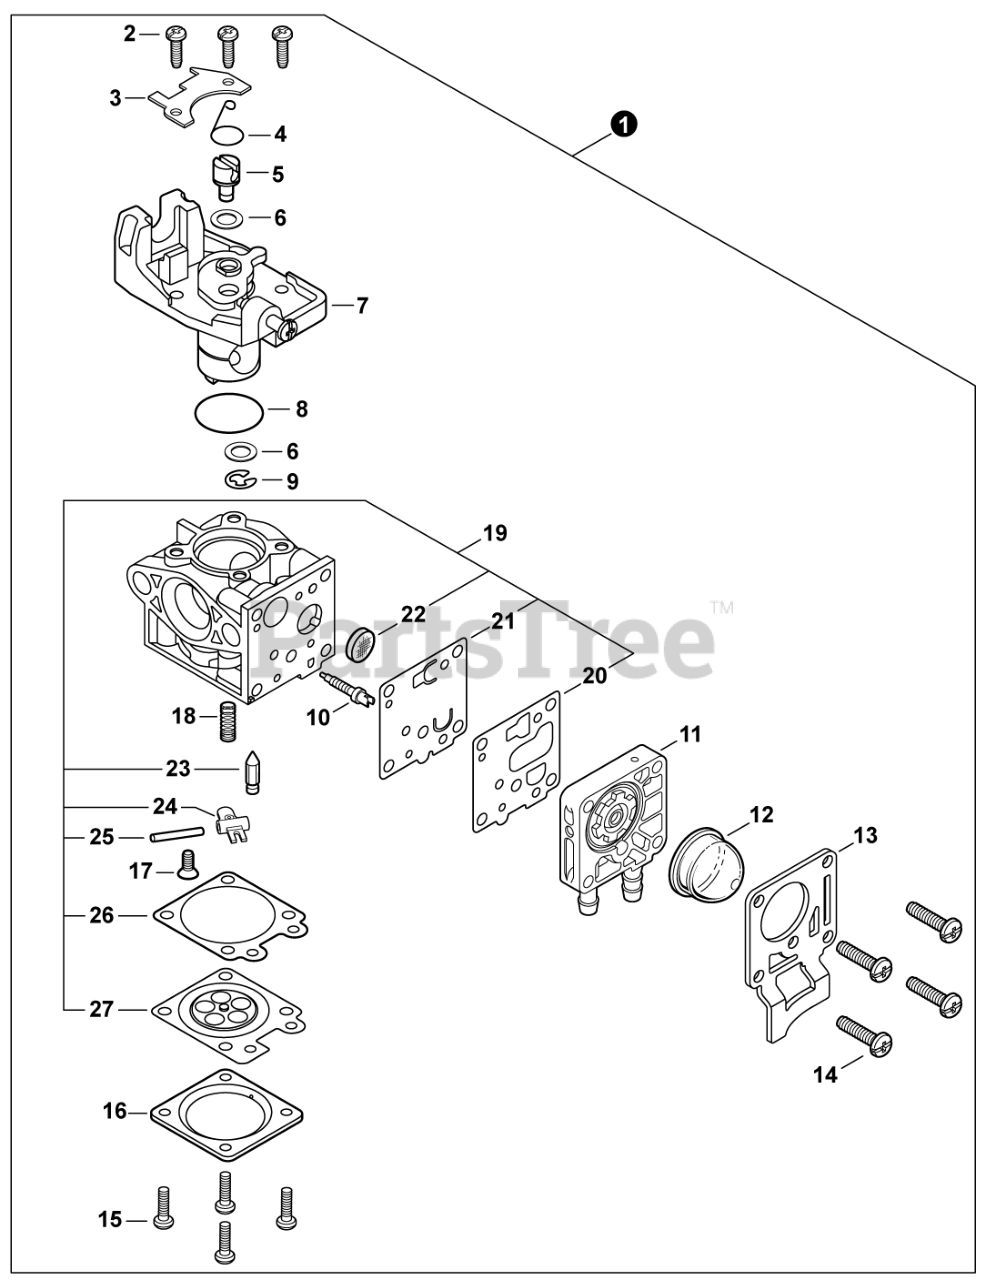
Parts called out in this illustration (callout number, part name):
1	CARBURETOR - WYG-11A
7	THROTTLE VALVE ASSY
10	NEEDLE, MIXTURE
11	BODY ASSY, PUMP
12	BULB, PURGE
13	COVER, FUEL PUMP
16	COVER, METERING DIAPHRAGM
19	REPAIR KIT, CARBURETOR
20	GASKET, FUEL PUMP
21	DIAPHRAGM, FUEL PUMP
22	SCREEN, FUEL INLET
23	VALVE, INLET NEEDLE
24	LEVER, METERING
25	PIN, METERING LEVER
26	GASKET, METERING DIAPHRAGM
27	DIAPHRAGM, METERING
